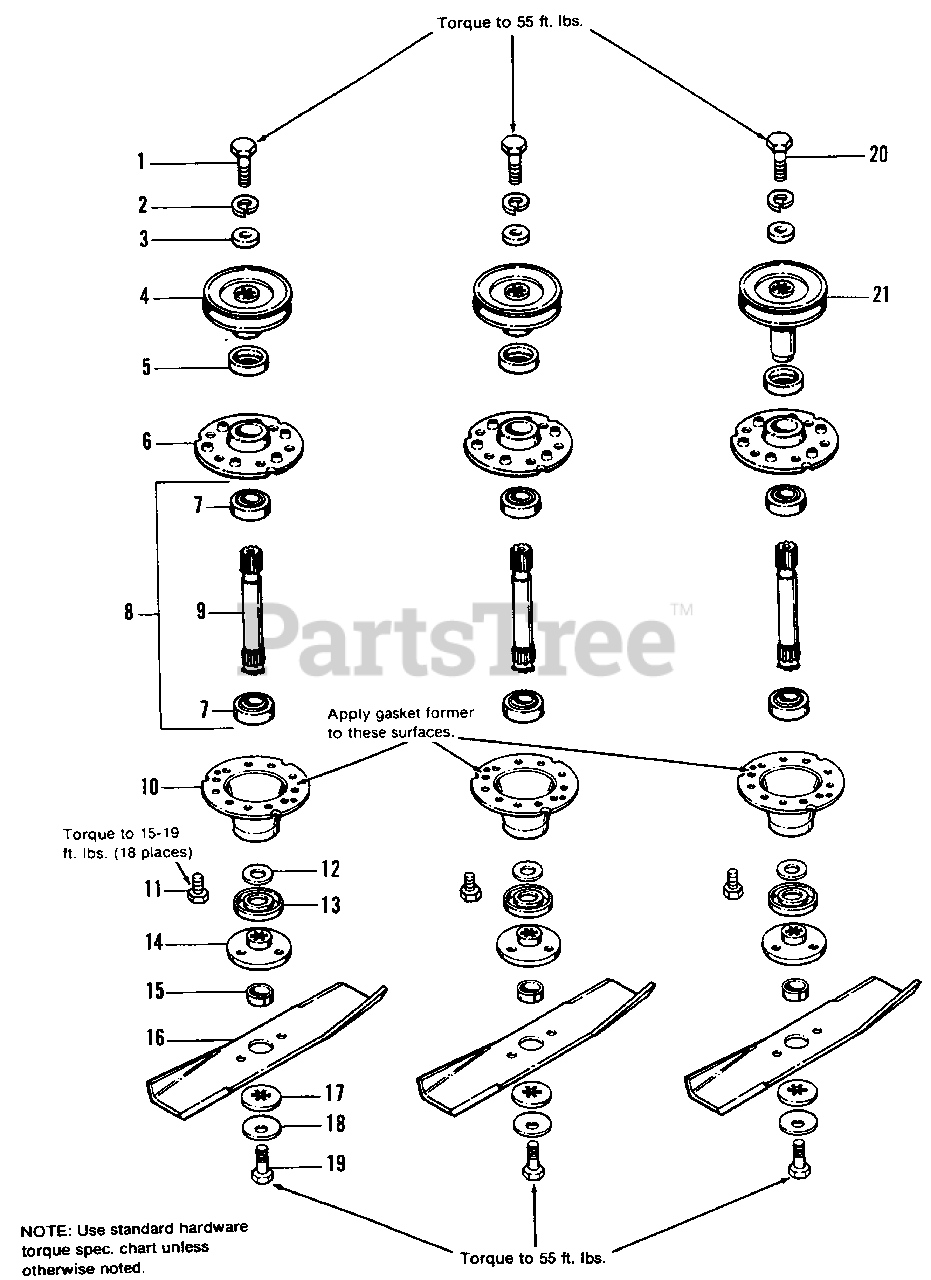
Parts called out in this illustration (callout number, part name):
1	CAPSCREW, hex 7/16-14 x 1-3/4
2	LOCKWASHER, 7/16
3	WASHER, Plain, 29/64 x 1-1/4 x 1/4
4	PULLEY ASSY.
5	SHIELD, Bearing Upper, Arbor
6	HOUSING TOP
8	SHAFT & BEARING ASSY. (Incl. Ref. No. 7)
9	SHAFT, Arbor
10	HOUSING, Bottom
11	SCREW, Hex, Taptite, 5/16-18 x 3/4
12	WASHER, Shim
13	SHIELD, Grass
14	ADAPTOR, Blade
16	BLADE, 42" Mower
17	WASHER, Spline
18	WASHER, Spring
19	CAPSCREW, Hex 7/16-14 x 1
20	CAPSCREW, Hex, 7/16-14 x 3-1/2
21	PULLEY ASSY.
